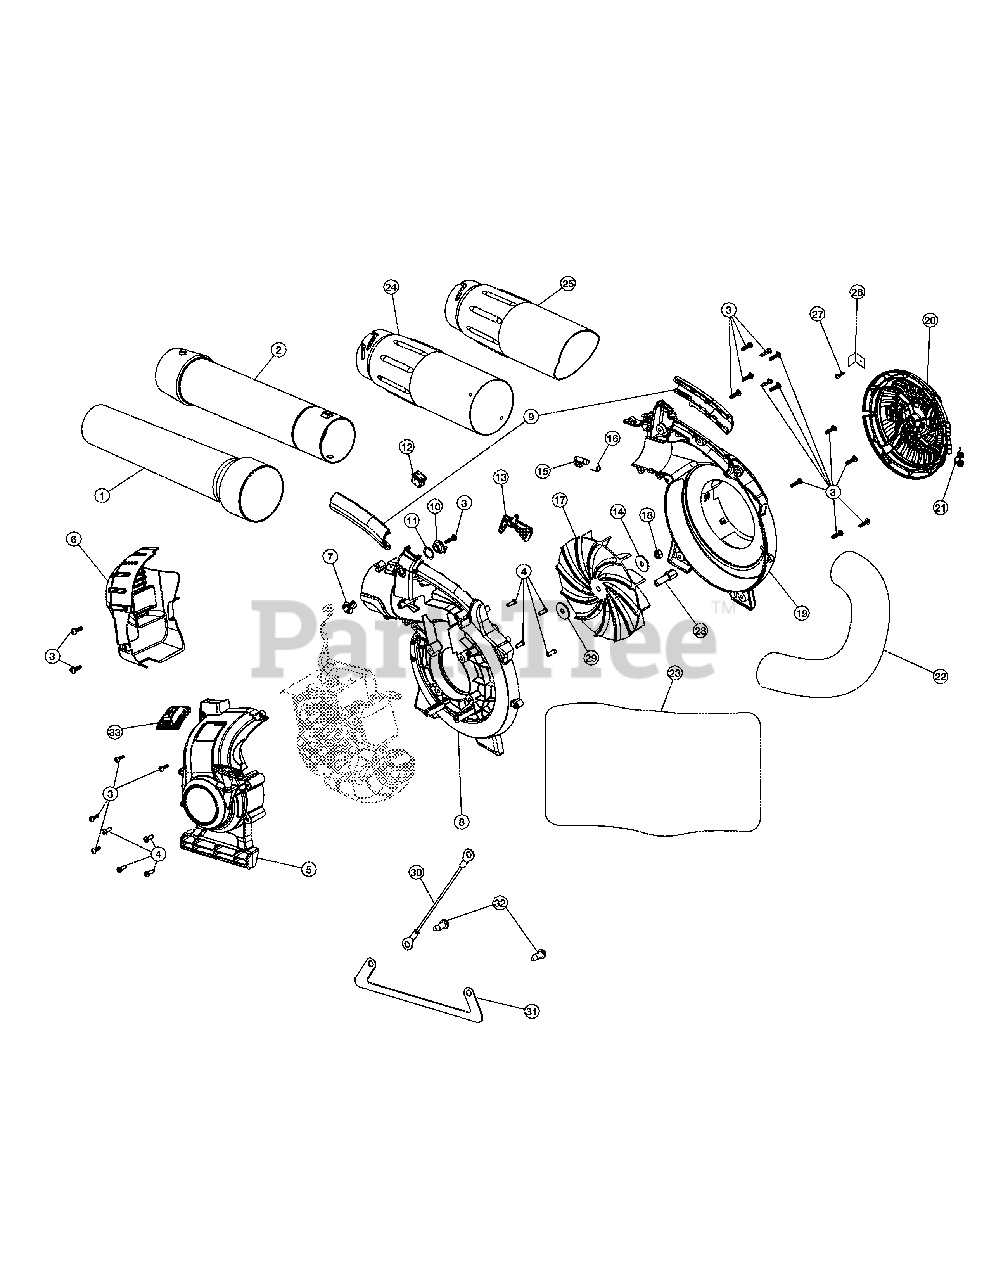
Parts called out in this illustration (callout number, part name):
1	Lower Tube
2	Upper Tube
5	Engine Cover Assembly (Incl. 3, 4 & 33)
6	Muffler Cover Assembly (Incl. 3)
7	Outer Trigger Lock
8	Impeller Housing
9	Handle Grips
10	Inner Trigger Lock
11	Wavey Washer
13	Throttle Trigger
15	Latch Tube
16	Latch Spring
18	Nut
19	Impeller Housing
20	Intake Cover
24	Upper Vac Tube
25	Lower Vac Tube
27	Screw
30	Wire Ground
31	Strap Ground
32	Screw
33	Spark Plug Cover
